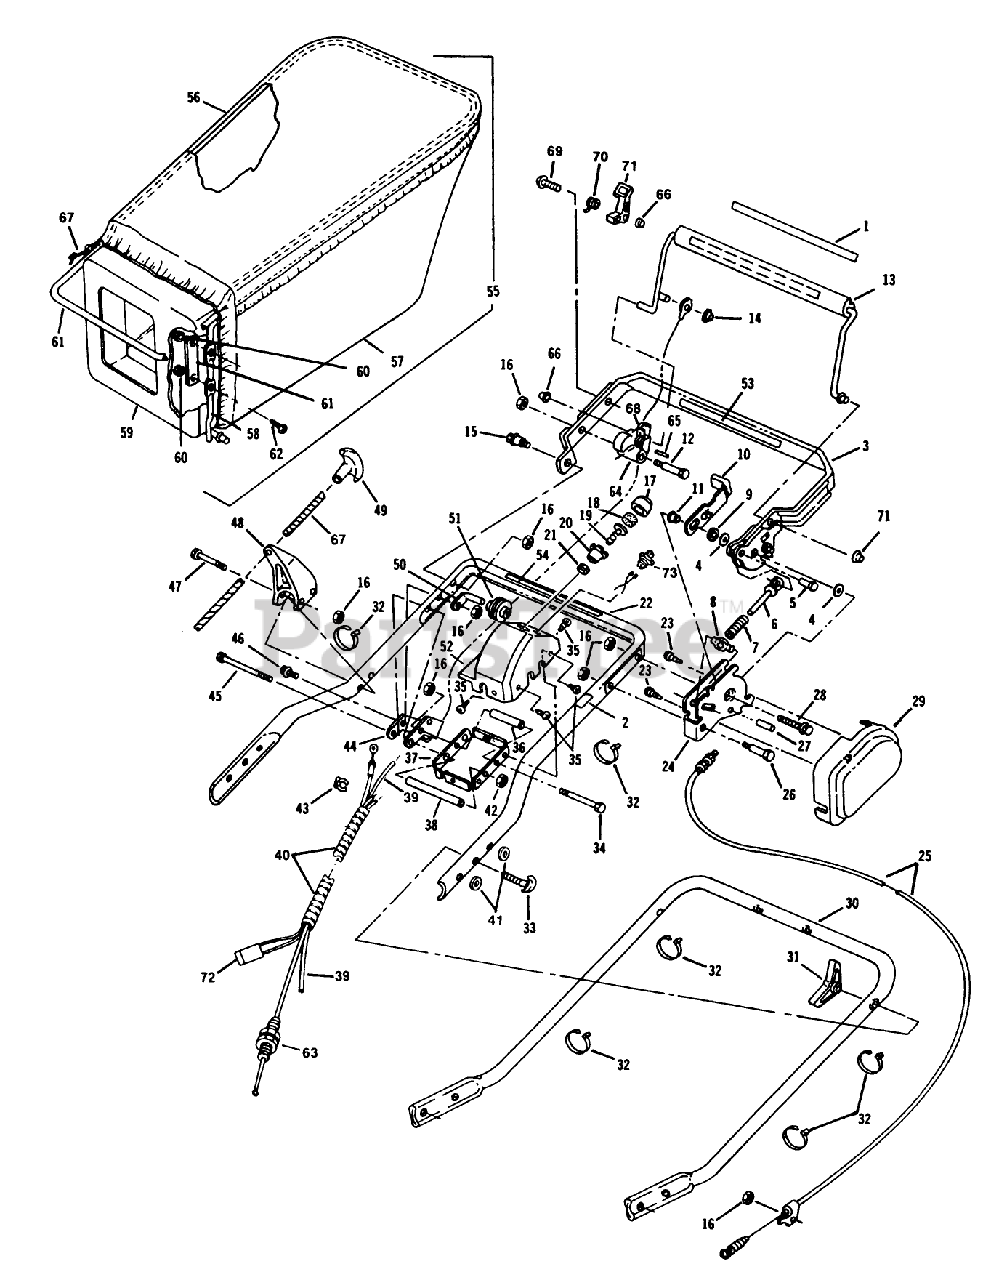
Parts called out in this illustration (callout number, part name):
9	WASHER M
14	NUT ACORN
15	BOLT
16	LOCKNUT E
18	FILTER S
21	LOCKNUT S
25	CABLE ASM
31	NUT-WING
35	SCREW F
36	SPACER
41	WASHER-CURVED
43	RET. RING
45	BOLT-CONSOLE
47	Screw-Truss Head
49	HANDLE STARTER S
56	HANGER BAG TROX
59	BAG ADAPTOR PL
60	LOCKNUT E
68	CAM
73	SWITCH AY
